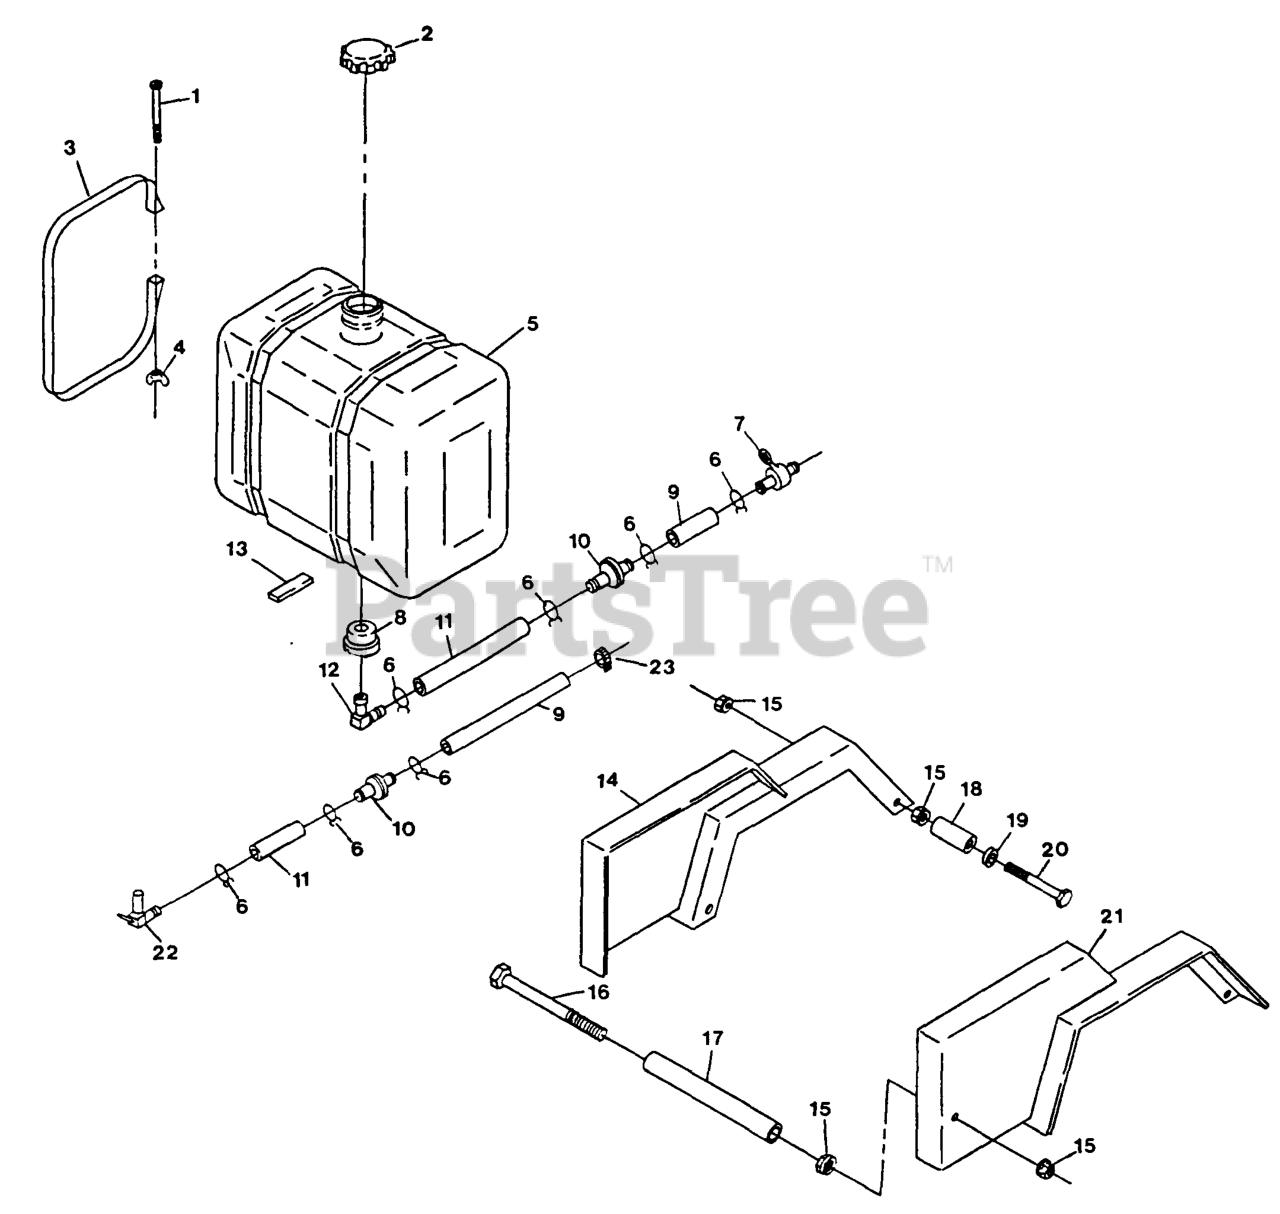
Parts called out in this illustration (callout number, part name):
1	SCRW,MACH CRPH
2	CAP-FUEL
4	WINGNUT
6	CLAMP
7	VALVE-FUEL
9	HOSE-LINE, FUEL
12	ELBOW-TANK, FUEL
13	PAD,PLASTIC TANK
18	SPACER-FENDER
23	CLAMP-HOSE
